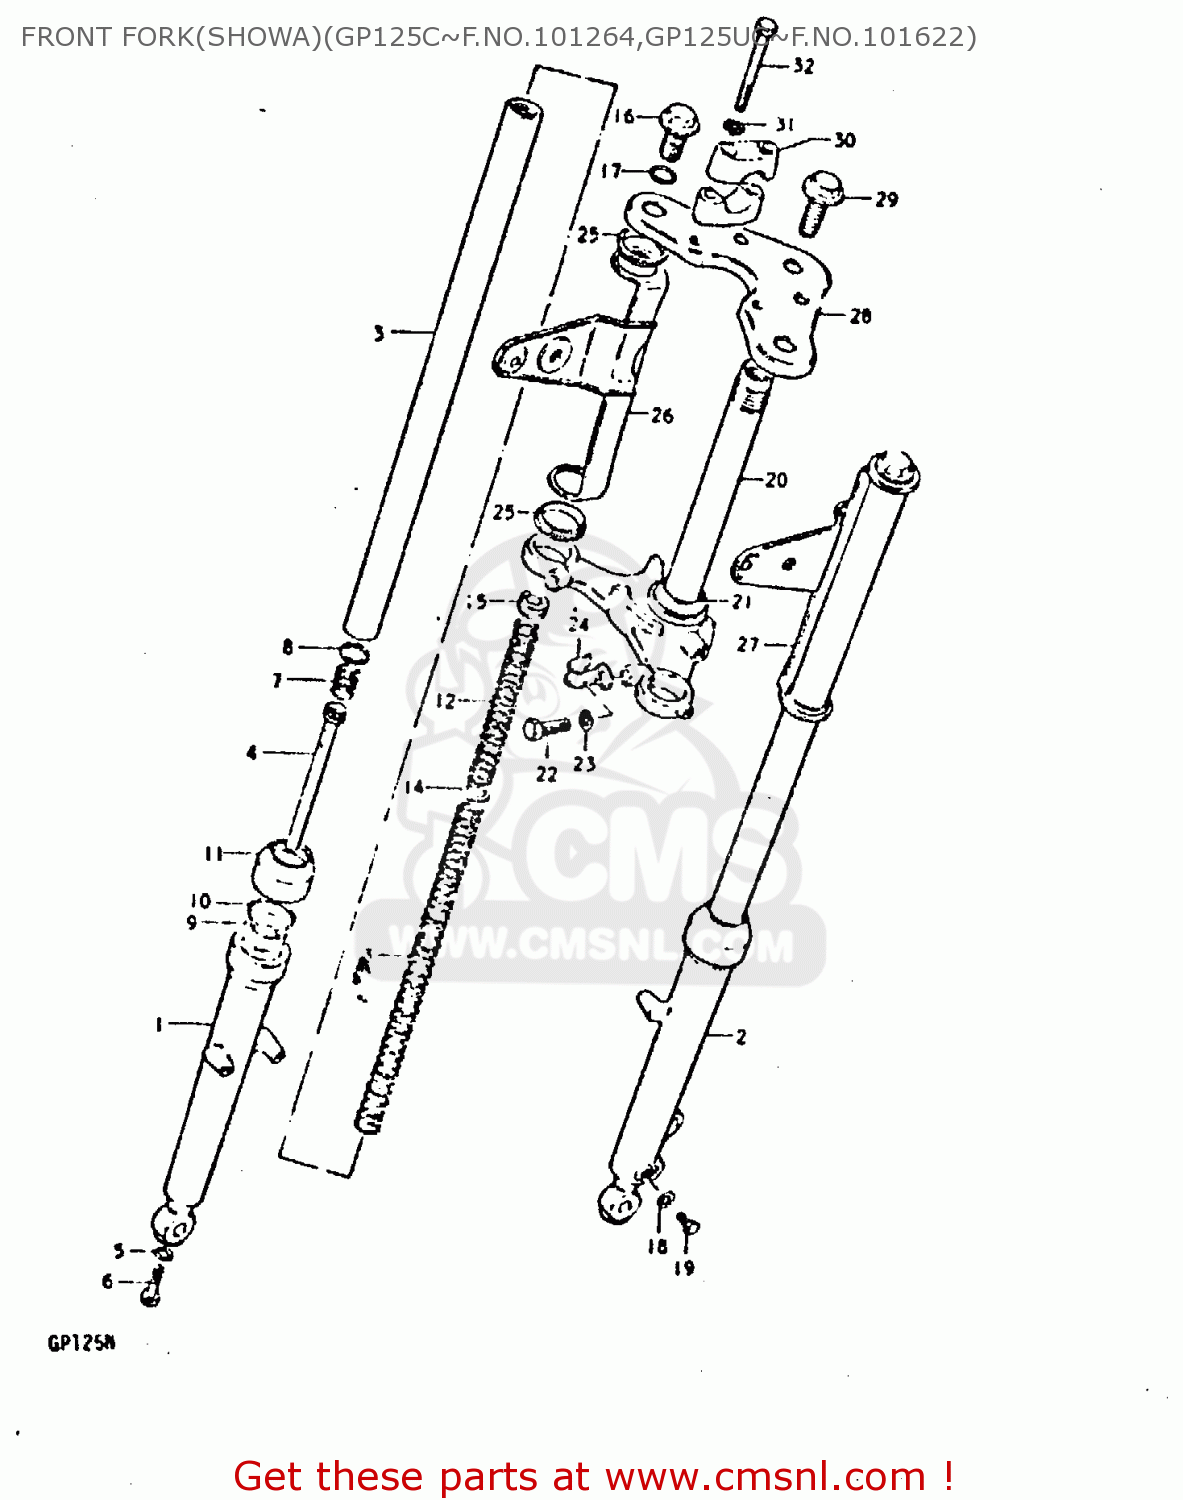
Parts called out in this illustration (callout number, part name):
1	OUTER TUBE, RH
2	OUTER TUBE, LH
3	TUBE, INNER
4	CYLINDER
5	GASKET (NAS)
6	BOLT
7	SPRING,REBOUND
8	RING,PISTON
9	OIL SEAL,FRONT FORK
10	RING,OIL SEAL STOPPER
11	BOOT
12	SPRING, NO.1
13	SPRING, NO.2
14	JOINT,SPRING
15	NUT,FORK SPRING,UPPER
16	CAP
17	O-RING,FORK INNER TUBE
18	GASKET,DRAIN,PLUG (NAS)
19	BOLT(6X8)
20	STEM, STEERING
21	RACE,STEERING OUTER LWR
22	BOLT 10X30
23	LOCK WASHER
24	CLIP,CABLE
25	CUSHION
26	BRACKET, HEADLAMP RH
27	BRACKET, HEADLAMP LH
28	STEM HEAD, STEERING
29	BOLT
30	HOLDER,HANDLE UPR
31	LOCK WASHER
32	BOLT 8X55
